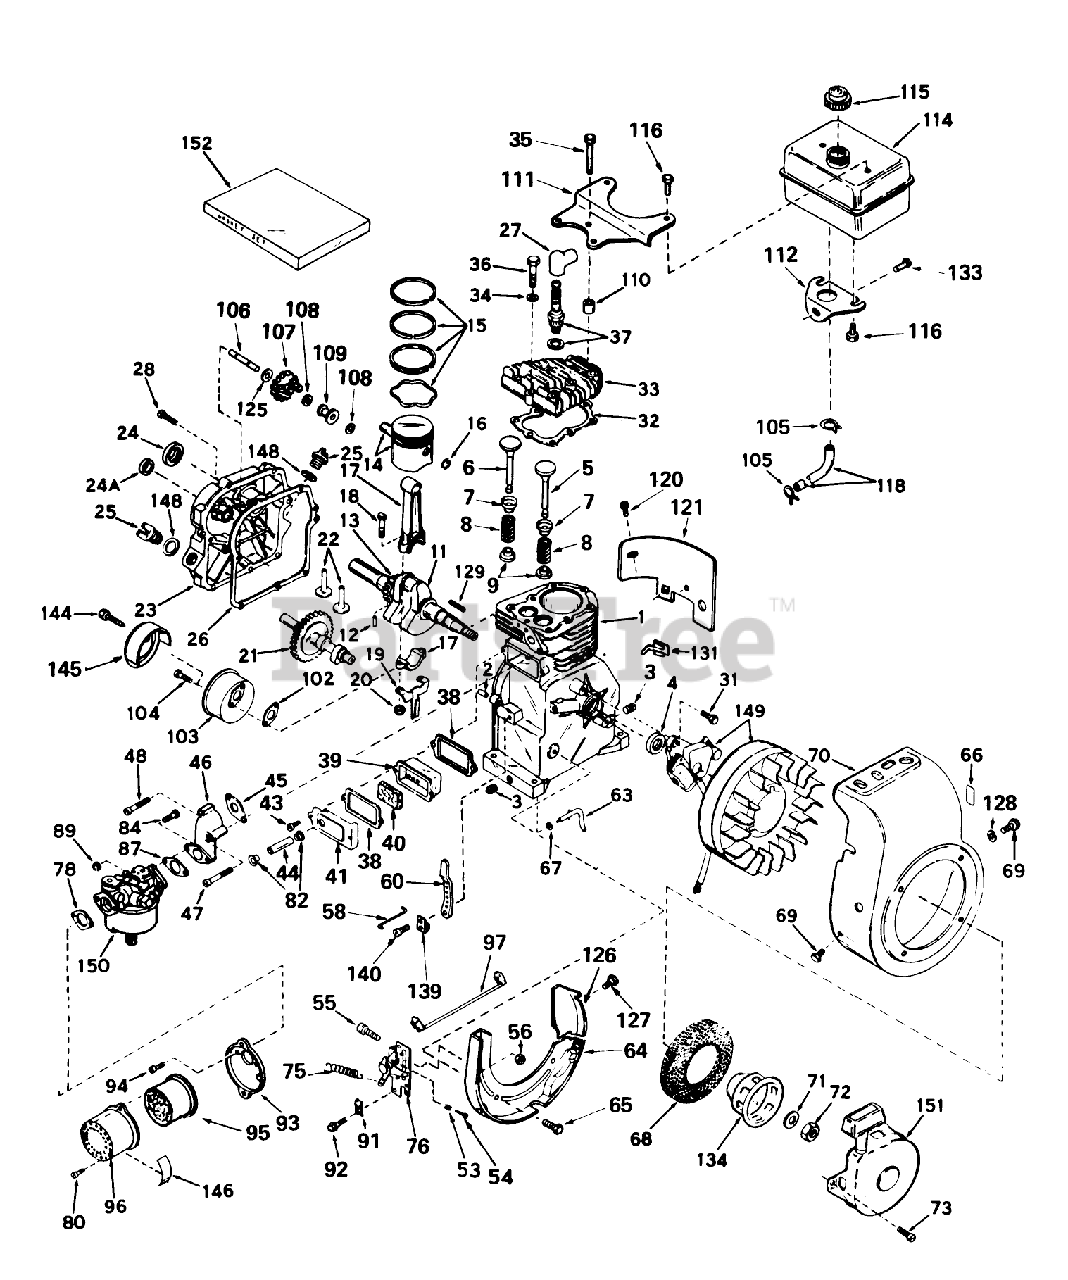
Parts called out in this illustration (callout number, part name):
1	Cylinder Assy. (Incl. Nos. 2,3 4)
2	Pin-Dowel
3	Plug-Drain, Oil (SQH 1/4-18)
4	OIL SEAL
5	Valve, Intake (Incl. Ref. #38, 39 40) (Std.)
5	Valve, Exhaust (1/32" Oversize) (Incl. Nos. 8, 9 10)
6	Valve, Exhaust (Standard) (Incl. Nos. 8, 9 10)
6	Valve, Exhaust (1/32" Oversize) (Incl. Nos. 8, 9 10)
7	Cap-Upper Valve Spring
8	Spring-Valve
9	Cap-Valve, Spring
11	Crankshaft Assy.
12	Pin, Groove
13	Gear, Crankshaft
14	Piston Pin Assembly (Incl. 2 of No. 16) (Std.)
14	Piston Pin Assembly (Incl. 2 of No. 16) (.010 Oversize)
14	Piston Pin Assembly (Incl. 2 of No. 16) (.020 Oversize)
15	Piston Ring Set Std.
15	Piston Ring Set .010 O.S.
15	Piston Ring Set .020 O.S.
16	Ring-Retaining, Piston Pin
17	Rod Assy., Connecting (Incl. Ref. #17)
18	Bolt, Connecting
19	53020/22 GIL.HYDRO
20	LOCKNUT
21	Camshaft, BCR, Extended
22	Lifter-Valve
23	Cover, Cylinder (Incl. Nos. 24, 25, 26, 106, 126 208)
24	Seal, Oil
24A	Seal, Oil
25	Plug-Fill, Oil
26	Gasket-Cylinder Cover
27	Cover-Spark Plug
28	Screw
31	Screw
32	Gasket-Cylinder Head
33	CYLINDER HEAD
34	Washer
35	Screw Hex Hd. Cap
36	Screw
37	Plug, Spark (J17LM or equiv.)
38	Gasket-Breather
39	Body-Breather
40	Element, Breather
41	Gasket-Gear Case
43	Screw
44	Breather Tube
45	Gasket-Intake
46	Pipe, Intake
47	Screw (1/4-20 x 1-19/32)
48	Screw
53	Spring-Compression
54	Screw
55	Screw, Hex Slotted Hd.
56	Nut-Lock
58	Jet-Main
60	Lever-Governor
63	Rod-Governor
64	Baffle-Blower Housing
65	Screw (1/4-20x19/32)
66	Decal, Name Instruction
67	Washer-Flat
68	Screen-Starter
69	Screw
70	Housing Blower
71	Washer-Spring
72	Hex Nut
73	Screw
75	Spring-Extension
76	Bracket Assy., Control (Incl. Nos. 149, 150, 151 152)
78	Gasket
80	Screw
82	GROMMET
87	Gasket
89	Nut and Lock Washer (1/4-28)
91	Conduit
92	Screw (10-32 x 3/8)
93	BRACKET, AIRCLEANER
94	Screw (10-32 x 1/2)
95	AIRCLEANER
96	Body
97	Wire, Ground
102	Gasket Exhaust
103	Muffler
104	Screw
105	Clamp-Line, Fuel
106	Shaft-Governor
107	Governor Gear ASM
108	Ring-Retaining
109	Spool-Governor
110	pacer
111	Bracket, Fuel tank
112	Bracket, Fuel Tank Lower
114	53023/VAR.10/16HP O
115	Cap, Fuel
116	Screw (1/4-15x7/8)
118	Line-Fuel
120	Screw
121	Extension-Blower
125	Washer-Flat
126	Baffle-Extension
127	Screw-Hex Washer Hd.
128	Washer
129	Key Flywheel
131	Clip-Wire
133	Screw (1/4-20x19/32)
134	Cup, Starter
139	Clamp-Lever, Governor
140	Screw
144	Screw (1/4-15x7/8)
145	Cover-Muffler
146	DECAL, AIRCLEANER
148	Gasket
149	Magneto (The complete magneto is not available as an assembly. The magneto number is shown for reference purposes only. Order component parts individually, as shown in parts list.)
150	Carburetor (Incl. Nos. 58 57)
151	Starter, Rewind
152	Gasket Set (Incl. items marked*
